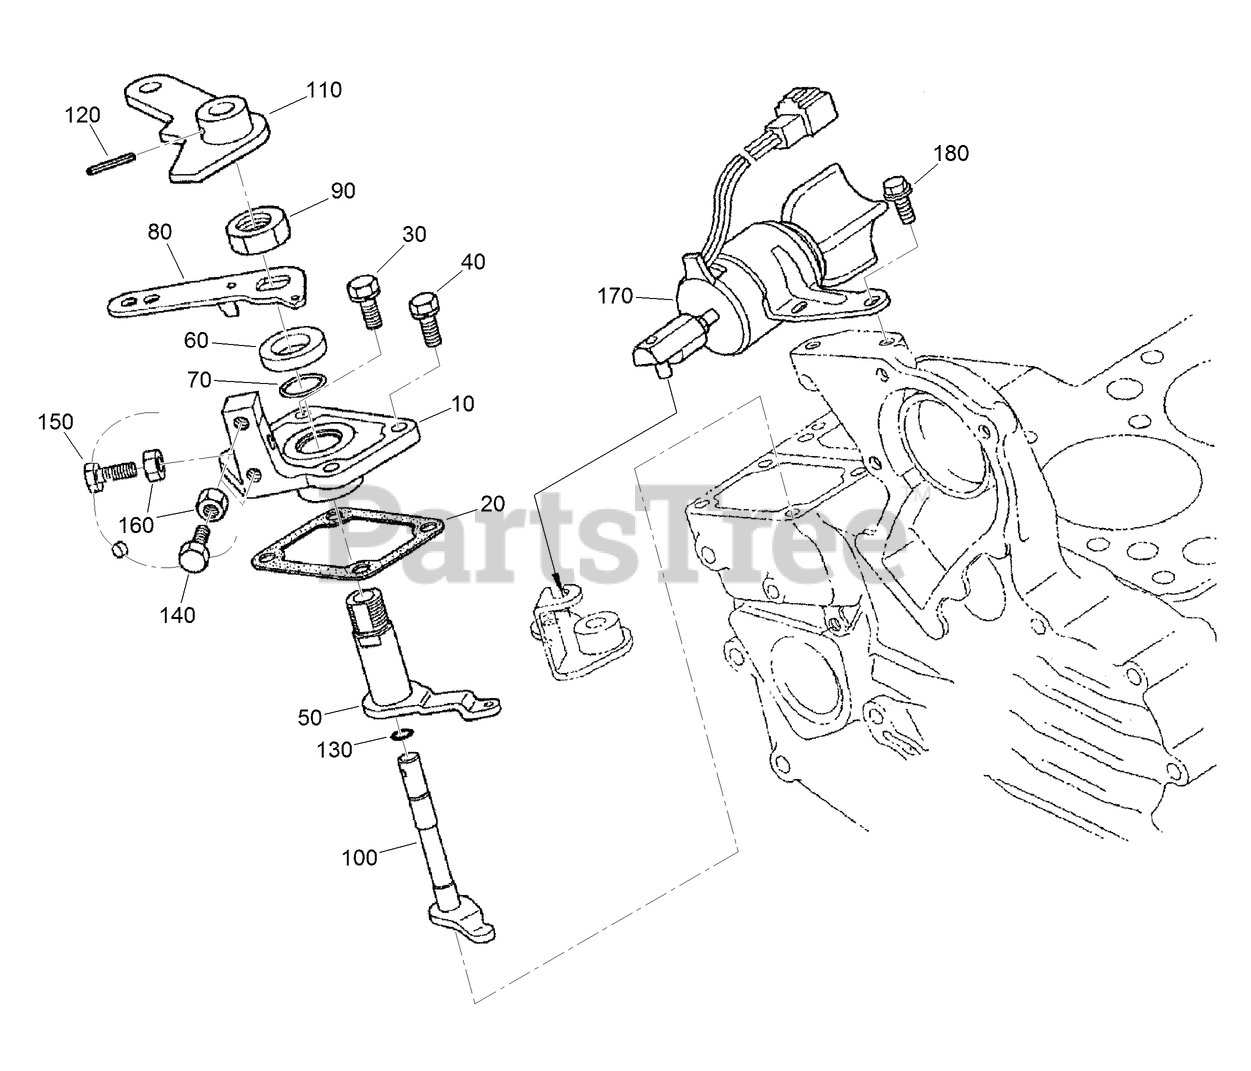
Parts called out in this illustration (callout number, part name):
10	PLATE-CONTROL, SPEED
20	GASKET-PLATE, CONTROL
30	BOLT-FLANGE
50	LEVER-GOVERNOR
60	COLLAR
70	O-RING
80	LEVER-CONTROL, SPEED
90	NUT-CONTROL, SPEED
100	SHAFT-LEVER
110	LEVER-STOP, ENGINE
120	PIN-SPRING
130	O-RING
140	SCREW-STOPPER
170	SOLENOID-SHUT OFF/ON
180	BOLT-FLANGE
